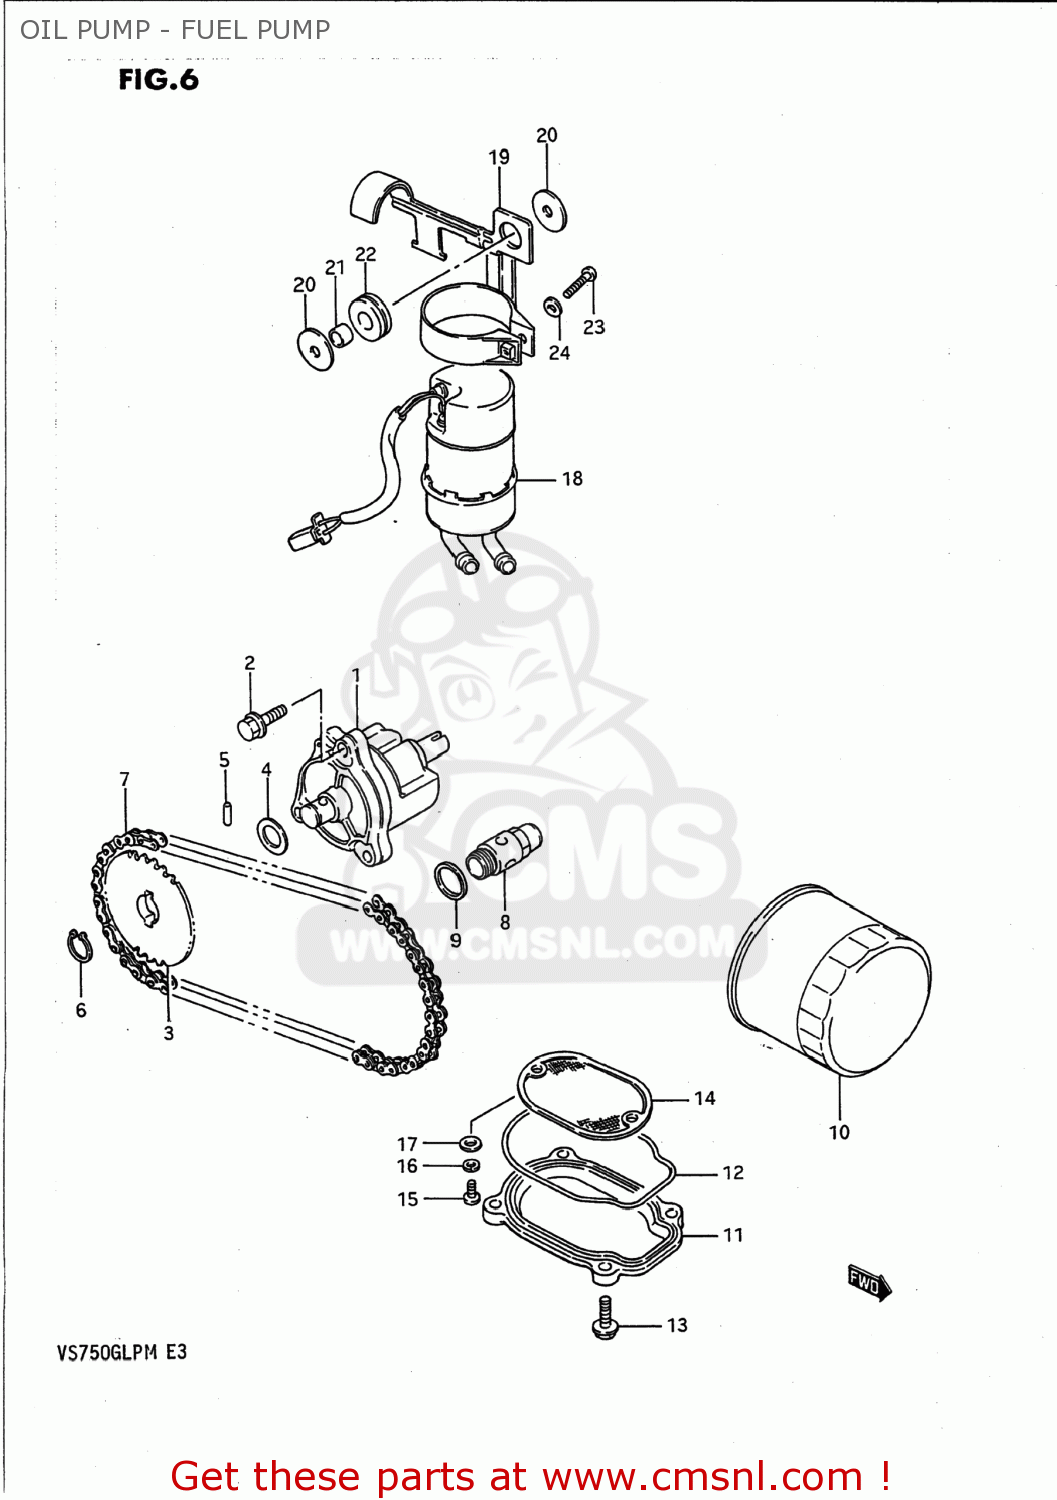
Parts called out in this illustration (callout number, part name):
1	PUMP ASSY,ENGINE OIL
2	BOLT 6X25
3	SPROCKET,OIL PUMP DRIVEN
4	SHIM
5	PIN(5X18)
6	CIRCLIP
7	CHAIN,OIL PUMP DRIVE
8	VALVE ASSY,OIL RELIEF
9	GASKET(16X22X2) (NAS)
10	FILTER,OIL
11	CAP,OIL STRAINER
12	O RING,OIL STRAINER CAP
13	BOLT 6X20
14	STRAINER,ENGINE OIL
15	SCREW 5X12
16	LOCK WASHER
17	WASHER
18	PUMP ASSY,FUEL
19	BRACKET,FUEL PUMP
20	WASHER (6.5X24X1.6)
21	SPACER(6.5X10.5X6.5)
22	CUSHION
23	SCREW
24	WASHER 4MM
